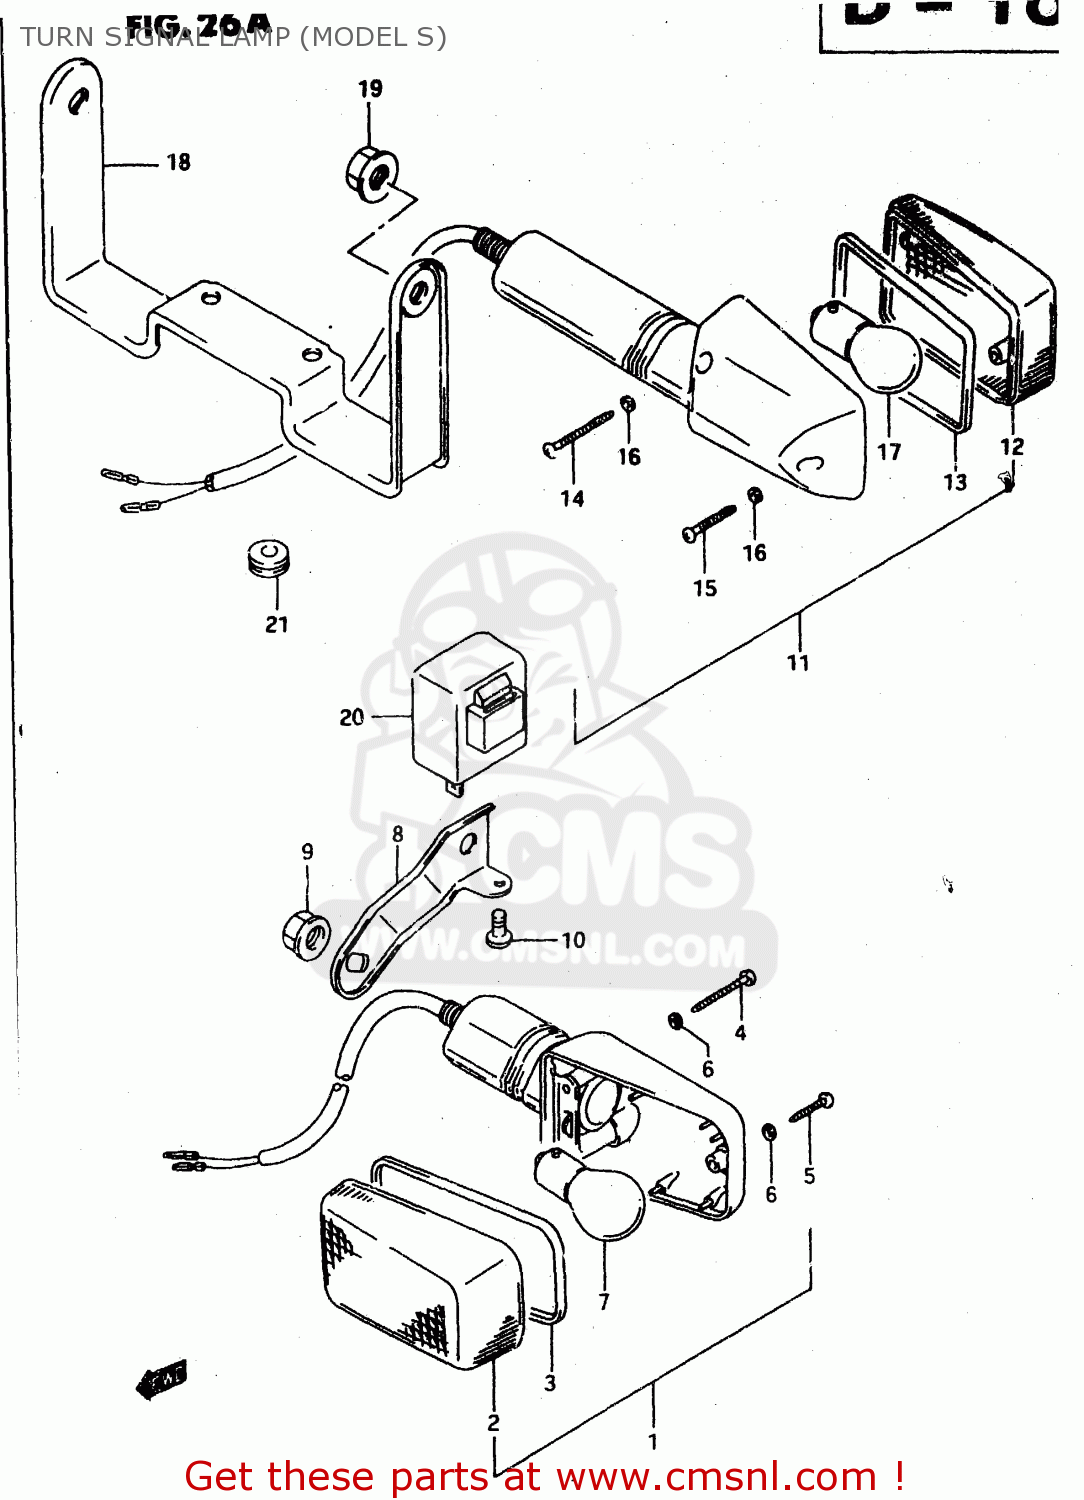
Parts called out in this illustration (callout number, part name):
1	LAMP ASSY,FR TURN SIGNAL
2	LENS
3	GASKET (NAS)
4	SCREW(3X30)
5	SCREW
6	GASKET (NAS)
7	BULB(12V21W)
8	BRACKET,FRONT TURN SIGNAL
9	NUT
10	SCREW
11	LAMP ASSY, REAR TURNSIGNAL
12	LENS
13	GASKET (NAS)
14	SCREW(3X30)
15	SCREW
16	GASKET (NAS)
17	BULB(12V21W)
18	BRACKET, REAR TURN
19	NUT
20	RELAY ASSY,TURNSIGNAL LAMP
21	GROMMET
